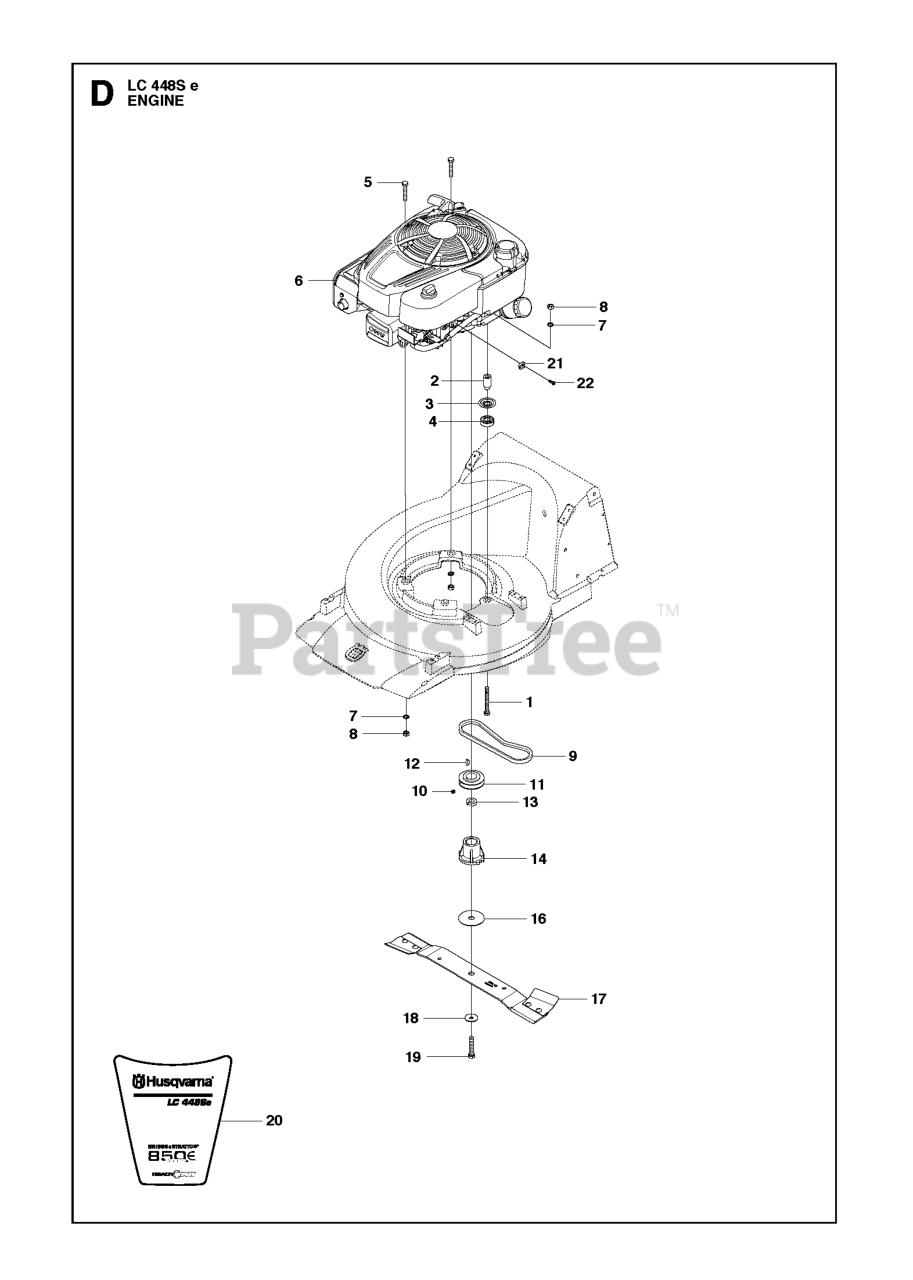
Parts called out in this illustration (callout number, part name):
1	Screw, Ehhm
7	WASHER BRB 8.4X17
8	LOCKNUT M8
